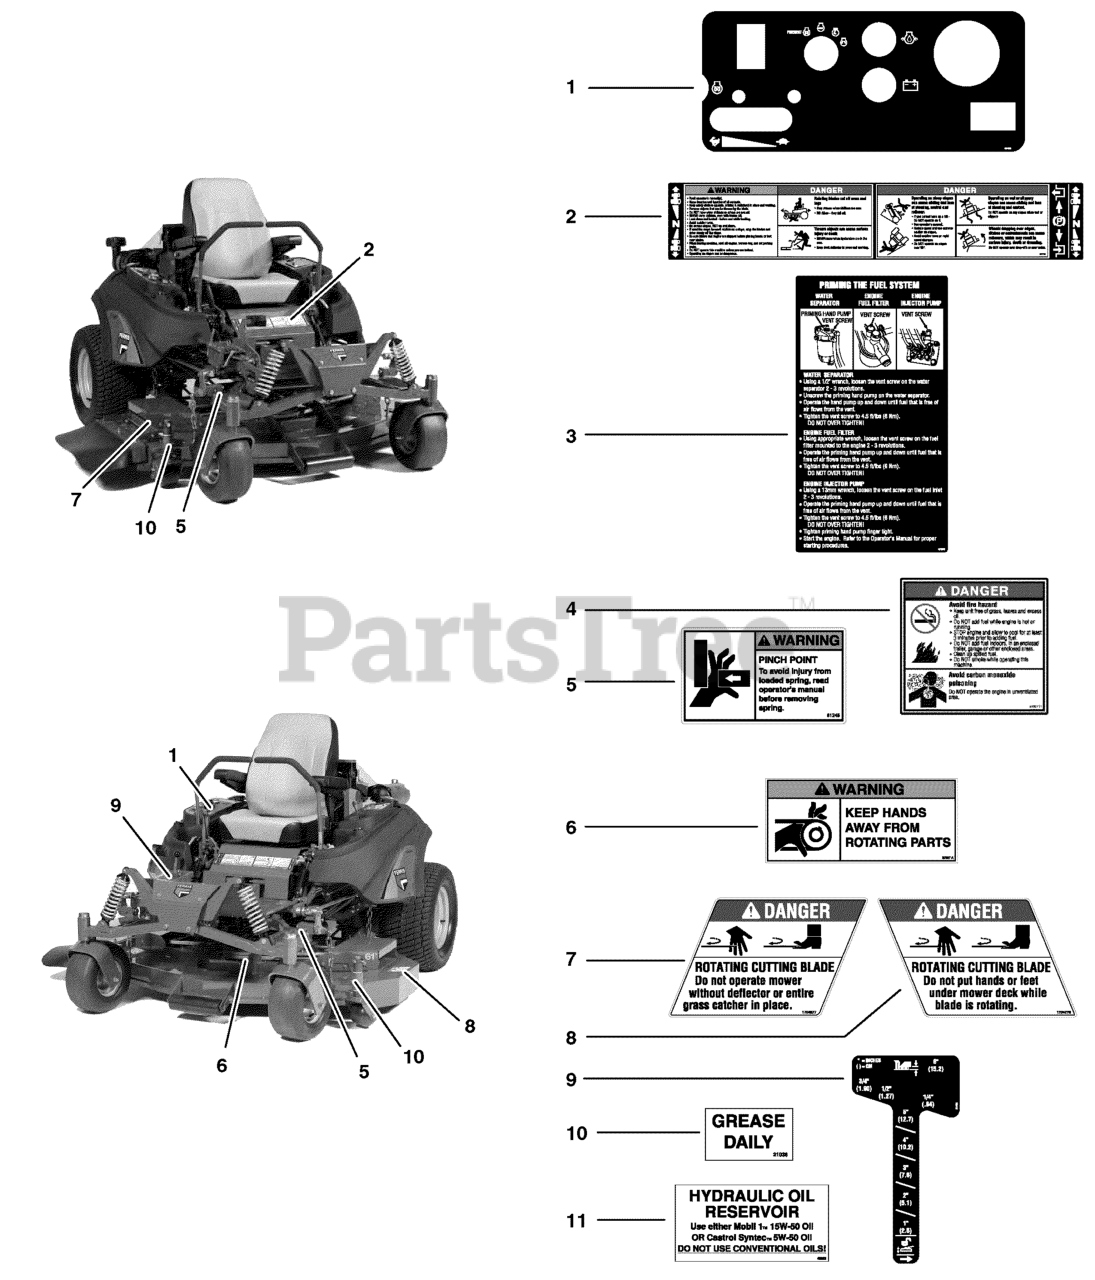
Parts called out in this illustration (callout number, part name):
1	DECAL, Control Panel, Diesel
2	DECAL, Main
3	DECAL, Priming Instructions
4	DECAL, Danger
5	DECAL, Pinch Point
6	DECAL, Warning
7	DECAL, Danger (Chute In Place)
8	DECAL, Danger (Hand Under Deck)
9	DECAL, Height of Cut
10	DECAL, Grease Daily
11	DECAL, Oil Reservoir
